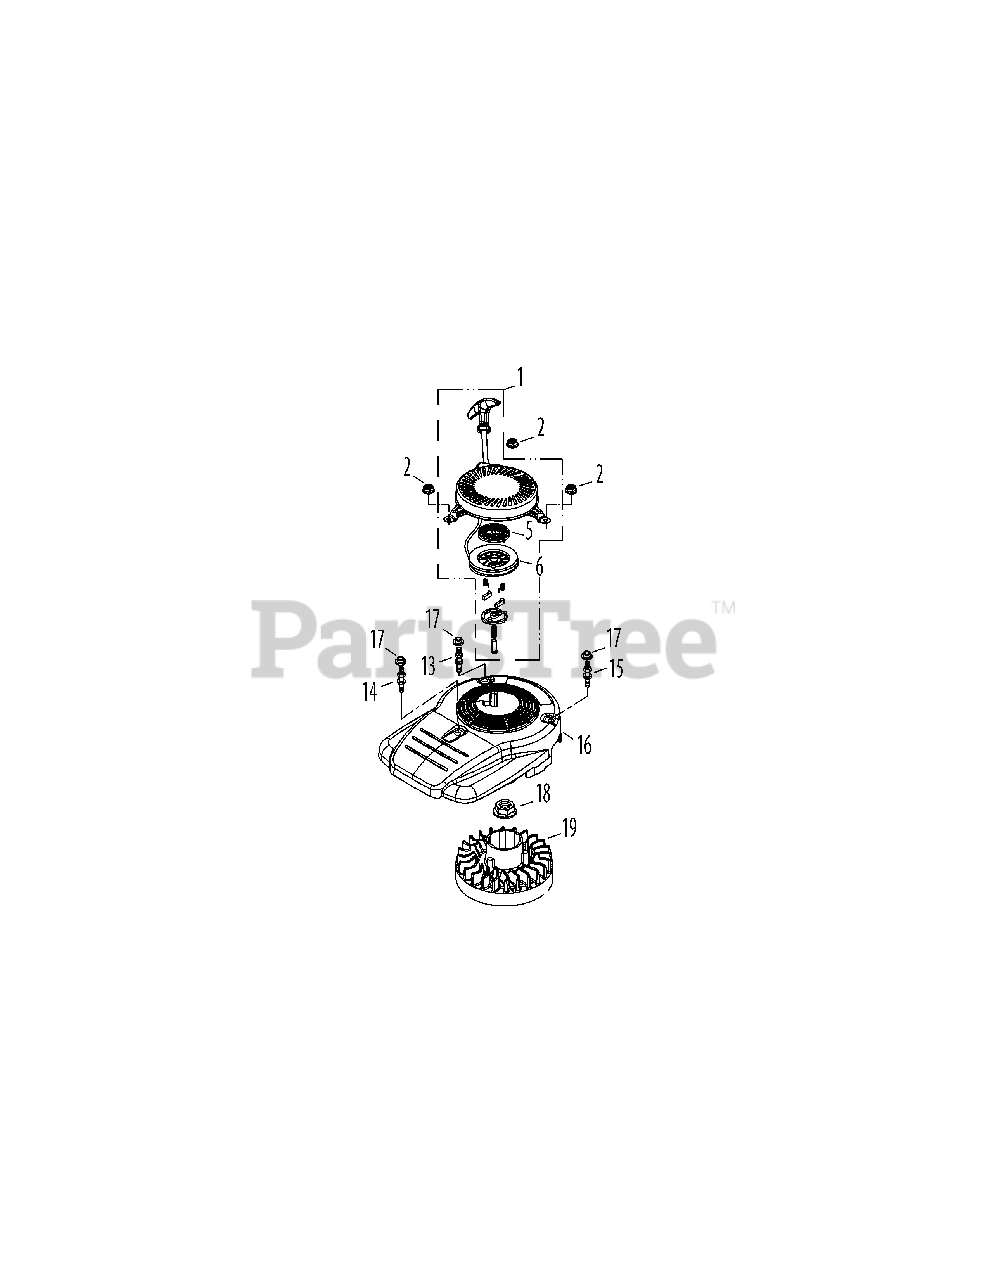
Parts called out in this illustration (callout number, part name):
1	Recoil Starter Assembly
2	Nut M6 X 10 Mm
5	Recoil Pulley & Spring Ass'y
6	Recoil Pulley & Spring Ass'y
13	Starter/Shroud Stud Black M6 x 75
14	Starter/Shroud Stud Front M6 x 75.3
15	Starter/Shroud Stud White M6-73
16	Engine Shroud (M0)
17	Engine Shroud Spacer
18	Flywheel Nut M14
19	Flywheel
